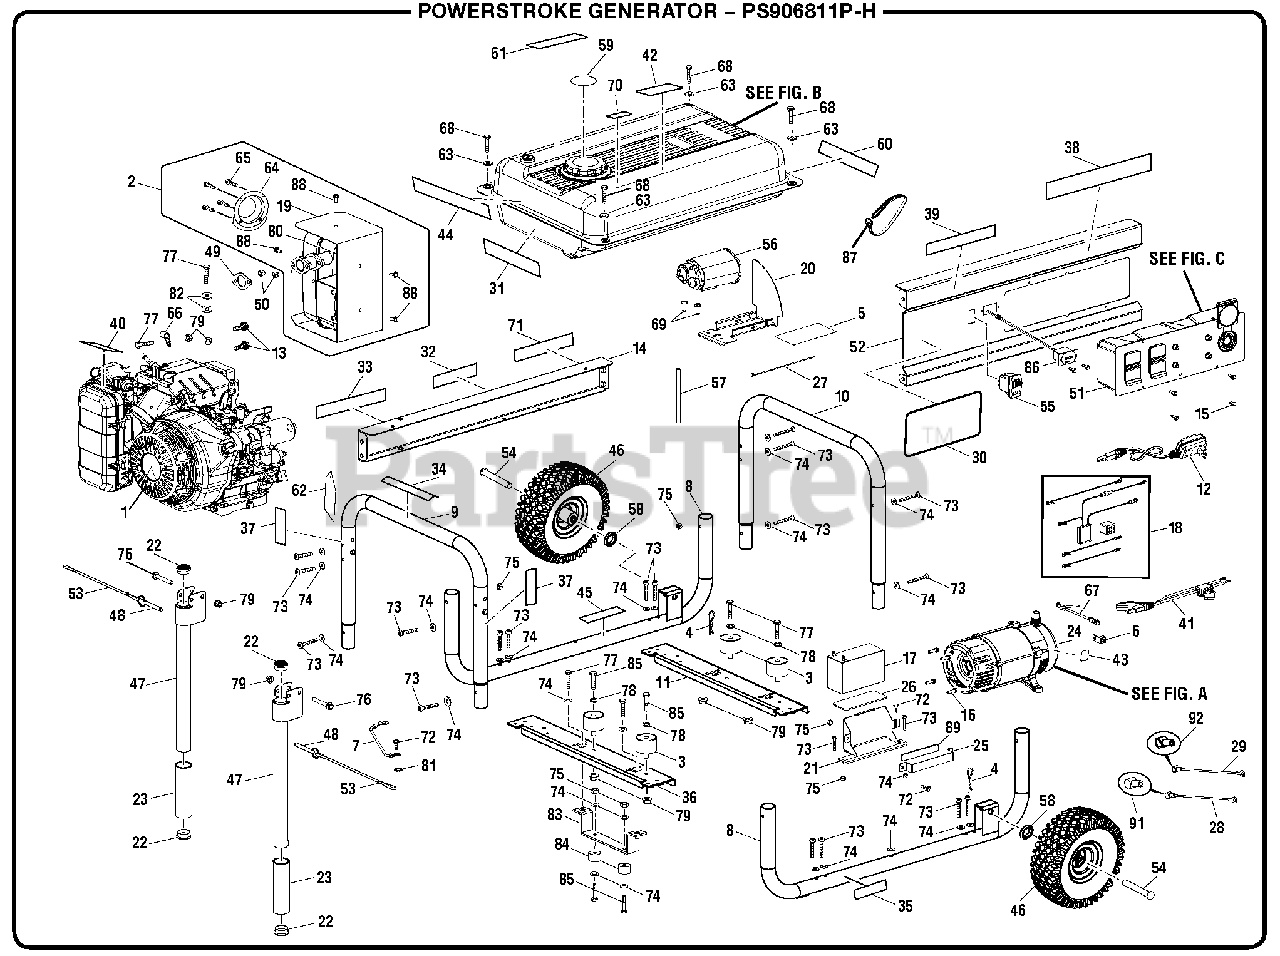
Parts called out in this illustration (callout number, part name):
2	Muffler Assembly
4	Hitch Pin
5	Rubber Sheet
6	Ground Lug
7	Ground Wire Assembly
8	Lower Frame Assembly
9	Tube Assembly (Left)
10	Tube Assembly (Right)
11	Cross Brace
12	Battery Charger
13	Bolt (5/16-24 x 5/8 in.)
14	Back Panel
15	Screw (6-20 x 3/8 in.)
16	Bolt (3/8-16 x 1-1/4 in.)
18	Wire Harness
19	Heat Shield
20	Bracket (Carbon Canister)
21	Battery Box
22	Plastic Cap
23	Handle Grip
24	Generator Head w/AVR
25	Battery Hold Down Bracket
26	Gasket (Battery Hold Down Bracket)
28	Battery Cable (Red)
29	Battery Cable (Black)
30	Logo Label
31	Electric Start Label
32	Hot Surface Label
33	Danger Label
34	Fire Danger Label
35	Engine Lubricant Label
36	Cross Brace
37	Locking Pin Label
38	Honda Label
39	Electric Start Label
40	Choke Label
41	Pigtail (DC)
42	CPSC Label
43	Ground Label
44	Inquires Label
45	Combustion Warning Label
47	Handle Assembly
48	Release Pin (5/16 x 2 in.)
49	Exhaust Gasket
51	Panel Assembly
52	Front Panel
55	Start Switch w/Lock
56	Carbon Canister Assembly
57	Purge Hose
58	Washer (1/2 in.)
59	Fuel Stabilizer Label
60	Ground Warning Label
61	Fuel Warning Label
63	Washer (1/4 in.)
64	Spark Arrestor
65	Screw (8-32 x 3/8 in., Pan Hd.)
66	J-Clamp (1/2 in.)
67	Bonding Wire
68	Screw (1/4-14 x 1-1/4 in.)
69	Screw (#10-16 x 3/4 in.)
70	E85 Label
71	Fire Distance Label
72	Screw (M6 x 16 mm, Hex Hd.)
73	Screw (M6 x 50 mm, T30 Torx Pan Hd.)
74	Washer (M6)
75	Lock Nut (M6)
76	Bolt (M8 x 55 mm, Hex Hd.)
77	Bolt (M8 x 35 mm, Hex Hd.)
78	Washer (M8)
79	Flange Lock Nut (M8 x 1.25)
80	Muffler
81	Star Washer (M6)
82	Washer (5/16 in)
83	Foot Bracket
85	Bolt (M6 x 25 mm, Hex Hd.)
86	Hour Meter
87	Cable Tie 18.6 in.)
88	Bolt (M6 x 9 mm)
89	Battery Bracket Gasket
90	Bolt (M6 x 25 mm, Hex Hd.)
91	Rubber Battery Cable Boot (Red)
92	Rubber Battery Cable Boot (Black)
